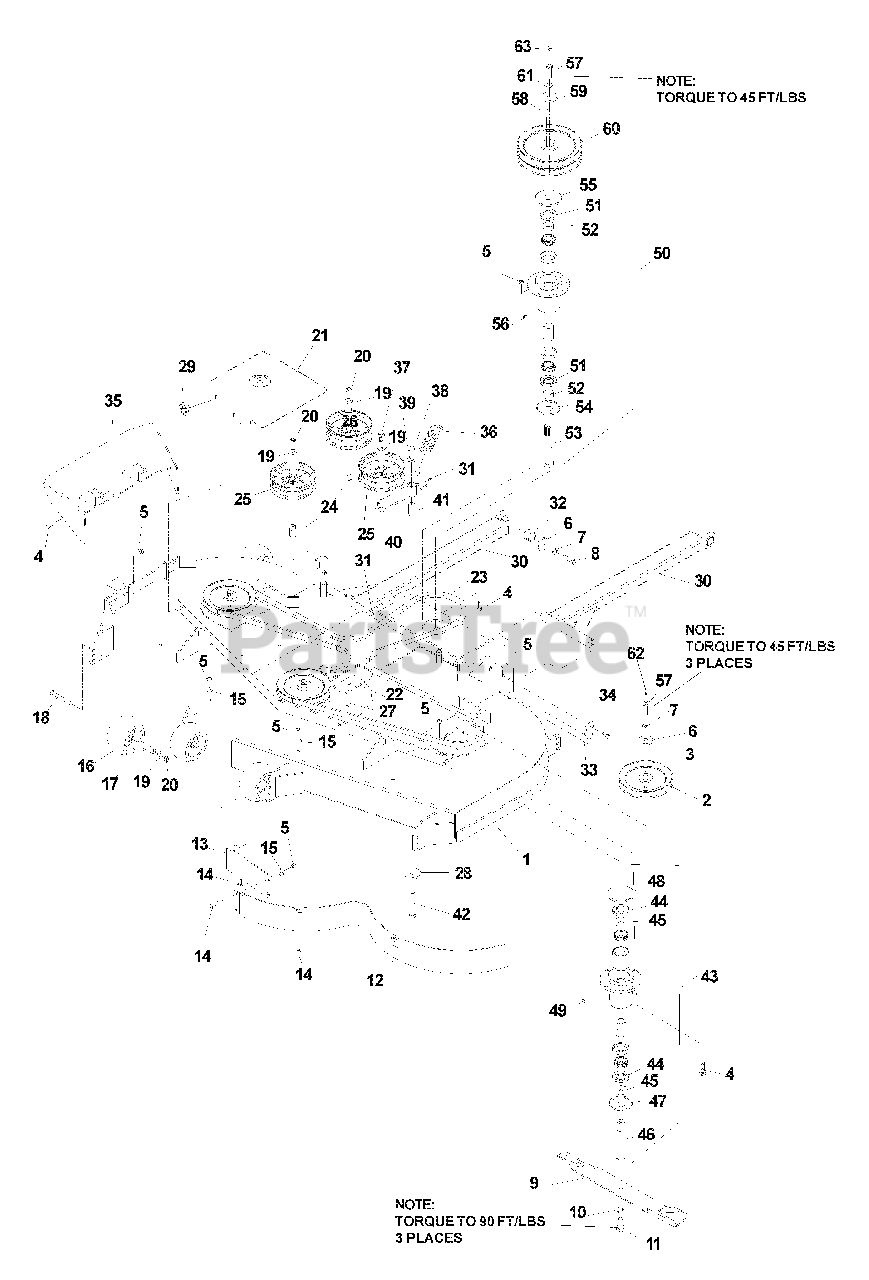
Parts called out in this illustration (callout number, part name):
1	61" Deck w/decals
2	Pulley
4	Bolt, 5/16-18 x 1
5	Nut, 5/16-18, centerlock
6	Washer, heavy
7	Lockwasher, 7/16
8	Bolt, 7/16-20 x 1 1/2
9	Blade, 21"
10	Lockwasher, 5/8
11	Bolt, 5/8-18 x 1 1/4
12	Main weldment
13	Baffle, center
14	Bolt, 5/16-18 x 5/8, carriage
15	Washer, 5/16
16	Anit-scalp roller
18	Bolt, 3/8-16 x 3 1/2
19	Washer, 3/8
20	Nut 3/8-16, centerlock
21	Belt shield, 61", right
22	Pad
24	Bushing, idler
25	Pulley, idler
26	Pulley, idler, tall
27	Bolt, 3/8-16 x 2 1/2
28	Washer, support
29	Knob, three prong
30	Strut weldment
31	Zerk
32	Spacer, strut
33	Pin weldment
34	Bolt, 5/16-18 x 3/4
35	Chute, discarge
37	Bolt, 3/8-16 x 1, ser.
38	Nut, 1/2-13, nyloc
39	Washer, 1/2
41	Bushing, pivot
42	Bolt, 1/2-13 x 3 1/4, GD. 5
43	Cutter housing, complete
44	Shaft seal
46	Mini spindle
47	Dust cap, bottom
48	Dust cap, top
49	Grease popet
50	Jackshaft assembly, lower
51	Shaft seal
53	Jackshaft spindle
54	Dust cap, bottom
55	Dust cap, top
56	Grease popet
57	Bolt, 7/16-20 x 1 1/2, GD. 5, special
58	Key, 1/4" sq. x 1 1/8"
59	Washer, heavy
61	Lockwasher, 7/16
62	Zerk
63	Zerk, 90°
